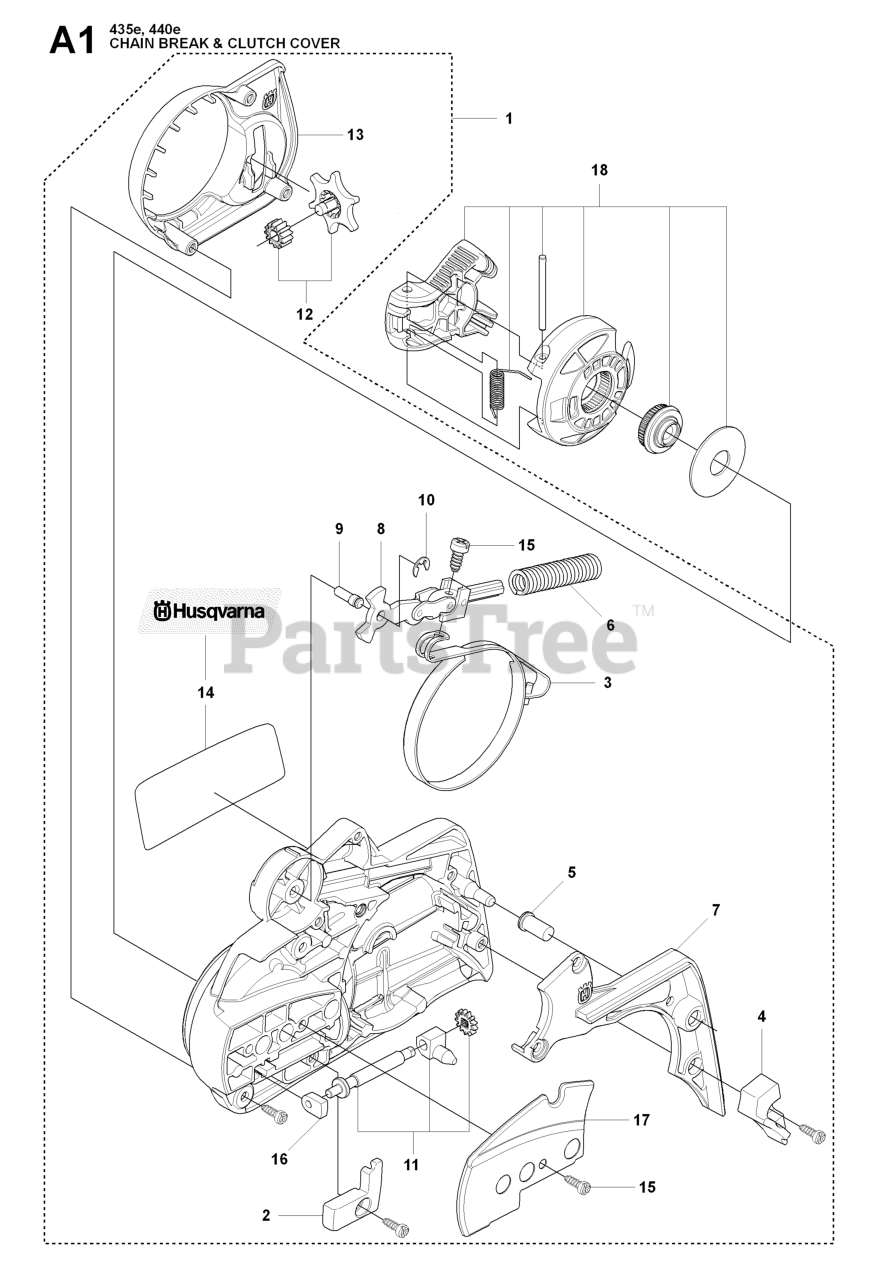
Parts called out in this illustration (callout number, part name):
1	CLUTCH COVER ASSY
3	BRAKE BAND ASSY
4	WEAR PROTECTION
6	BRAKE SPRING
11	CHAIN TENSIONER SCREW, COMP.
12	CHAIN TENSIONER WHEEL, COMP.
13	HEAT SHIELD
14	DECAL, CLUTCH HOUSING
16	RP BEARING SLEEVE
18	KNOB, COMPLETE
